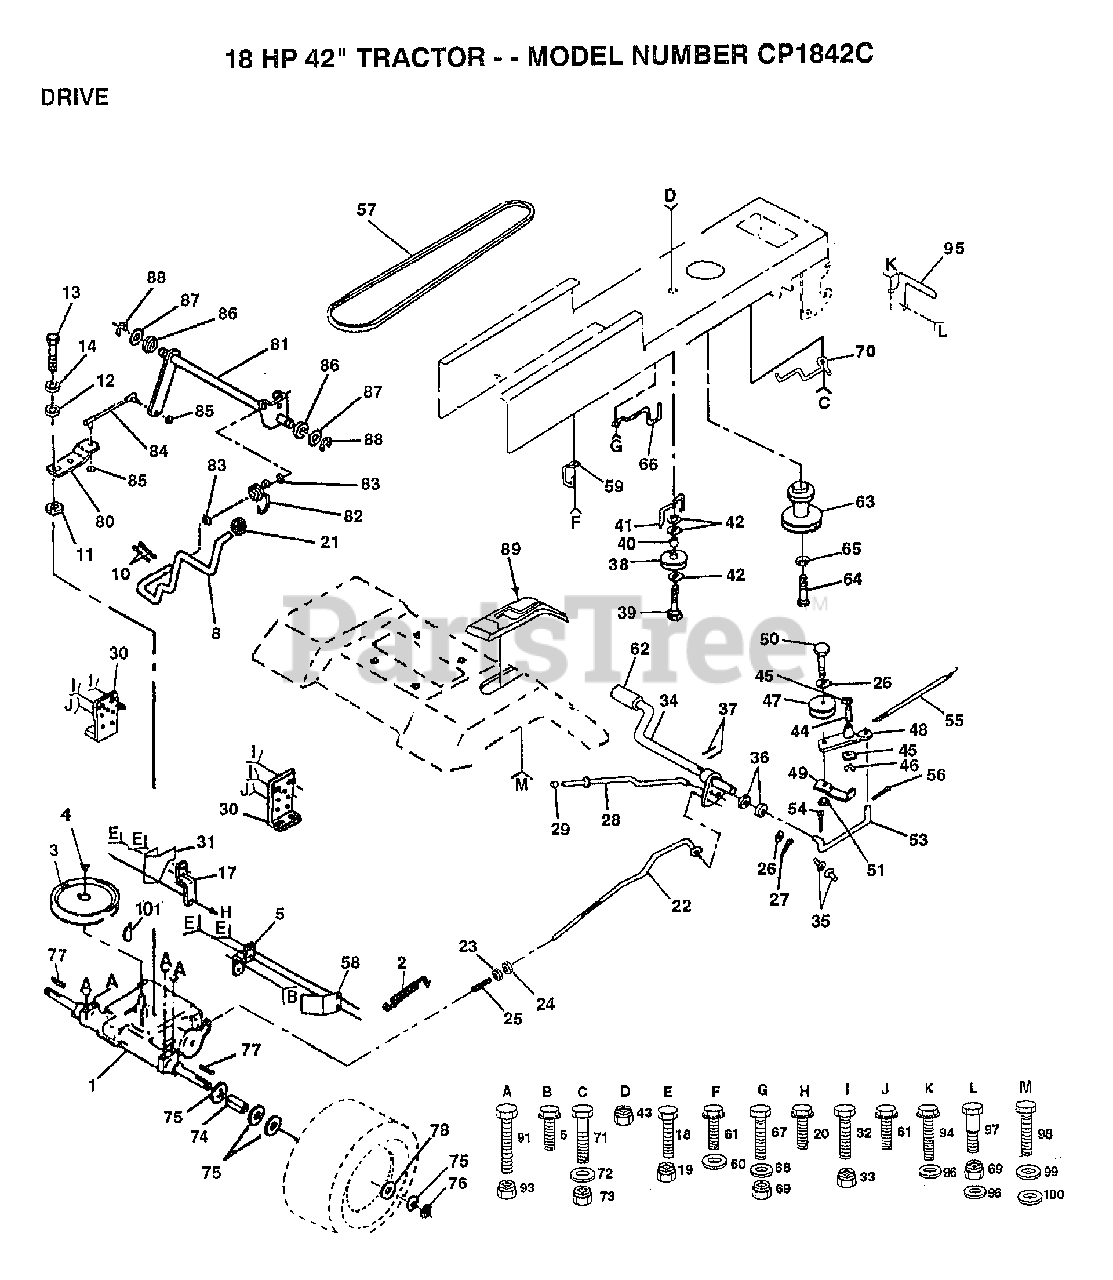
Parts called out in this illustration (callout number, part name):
3	"PULLEY,TRANSAXLE"
5	STRAP TORQUE
6	SCREW
8	"ROD,SHIFTER "
10	PIN COTTER 1/8
11	WASH-SHFT PLT LT
12	WASHER
14	LOCKWASHER
17	STRAP TORQUE
20	SCREW
21	KNOB T (1/2-HOLE)
22	BRAKE ROD
23	NUT
24	NUT
25	SPRING ROD LT
26	WASHER
27	COTTER PIN
28	BRAKE PARK ROD
29	PLUNGER CAP T
30	TRANSAXLE MTG BKT
31	"KEEPER,BELT LH"
32	BOLT
35	NYLON BEARING
36	WASHER LT
38	PULLEY.IDLER.FLAT
39	BOLT
40	SPACER T
41	BELT KEEPER LT
42	WASHER
44	"LY, BEARING"
45	WASHER LT
46	KLIP RING
48	ARM IDLER
49	RETAIN BELT
53	"LINK, CLUTCH T"
54	COTTER PIN
55	"SPRING, RETURN LT"
56	COTTER PIN
57	BELT-V
58	"KEEPER,BELT RH"
60	WASHER
61	SCREW
62	PEDAL COVER T
64	BOLT
65	LOCKWASHER
66	KEEPER.BELT.ENG.L
67	BOLT
68	WASHER
70	KEEPER BELT ENG
71	BOLT
72	WASHER
74	SPACER LT
75	WASHER
76	E-RING LT
77	SQUARE KEY
78	WASHER
80	ARM SHIFT TRANS
81	SHAFT ASM.SHIFT
82	"SPRING,TORSION"
83	WASHER
84	TIE ROD
85	NUT 1/4-28
86	BUSHING
87	WASHER D
88	KLIP RING
91	BOLT
94	SCREW GTV
95	MUFFLER GUARD
96	WASHER HYT
97	BOLT D
98	SCREW
99	"WASHER,LOCK"
100	WASHER
